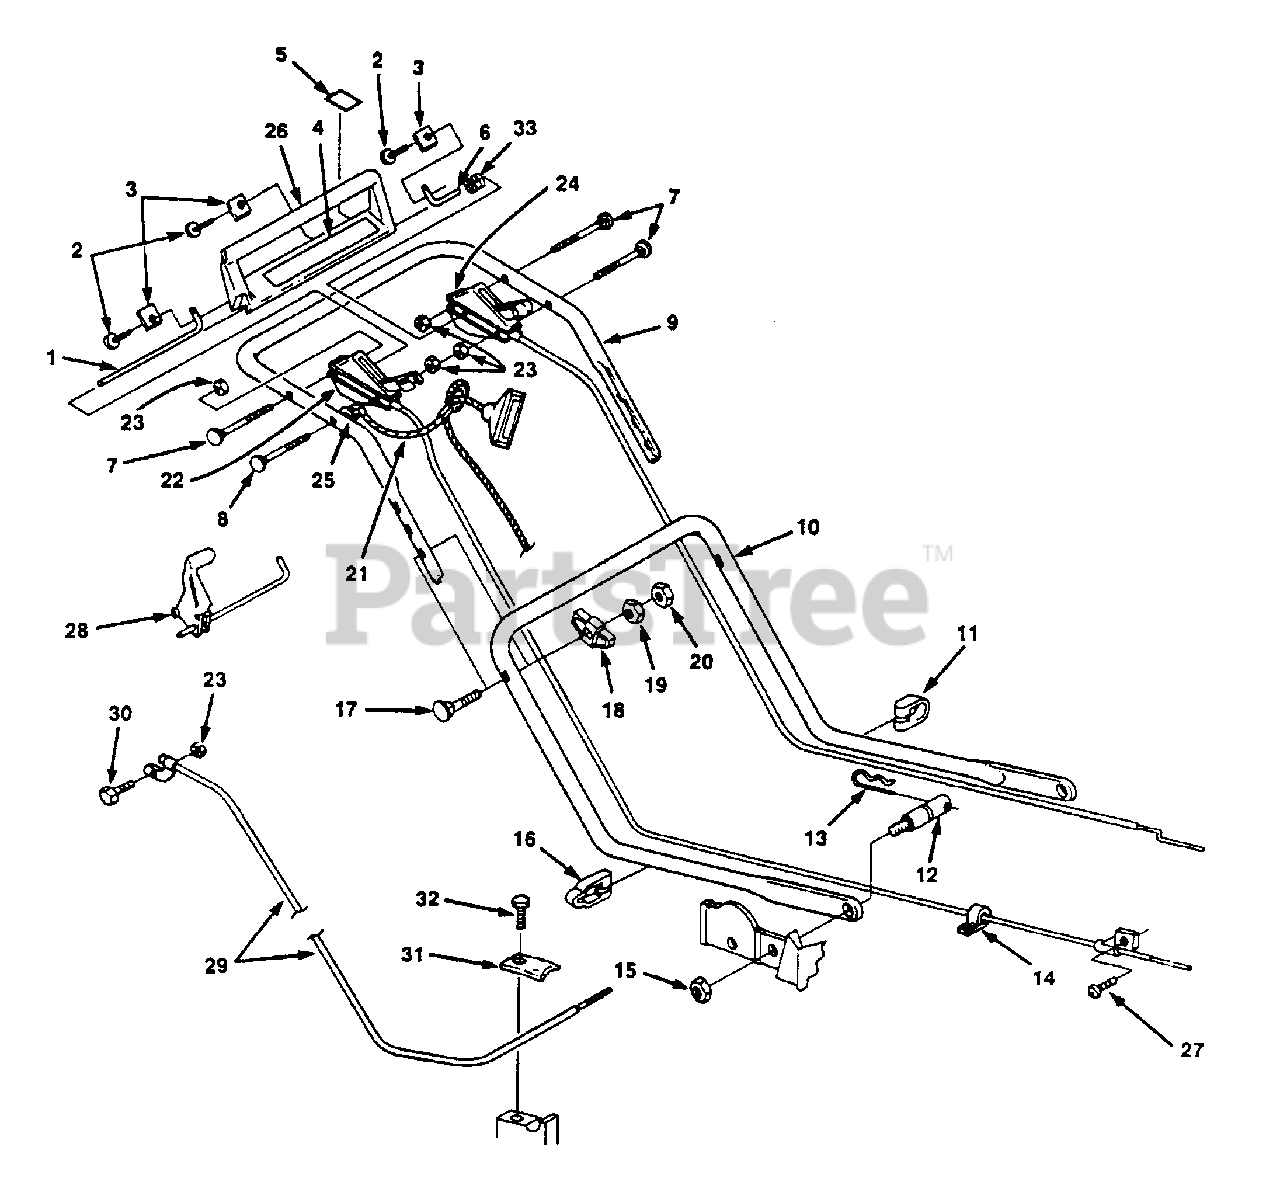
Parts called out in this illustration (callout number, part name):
1	SHAFT, PIVOT (LONG)
2	SCREW - 1/4-10×5/8" -- ROUND HEAD
3	CLAMP, PIVOT SHAFT
4	LABEL - BRAKE BAIL
5	LABEL - BLADE ROTATION
6	SHAFT, PIVOT (SHORT)
7	BOLT, SQ. NECK 1/4-20×2
8	BOLT, SQ. NECK 1/4-20×2 1/4
9	HANDLE - UPPER
10	HANDLE, LOWER
11	CLAMP - CABLE SINGLE
12	STUD
13	PIN, COTTER
14	CLAMP
15	NUT - 5/16-18 -- FLANGE
16	CLAMP - DOUBLE
17	BOLT
18	KNOB - HANDLE
19	NUT - 5/16-18
20	LOCKNUT - 5/16-18
21	ROPE, RESTRAINT
22	CONTROL, MANUAL START
23	LOCKNUT - 1/4-20
24	CONTROL, THROTTLE
25	WASHER - CARVED
26	BAIL - BRAKE CONTROL
28	TRACTION LEVER
29	CABLE, TRACTION
31	CLAMP
33	SPRING
